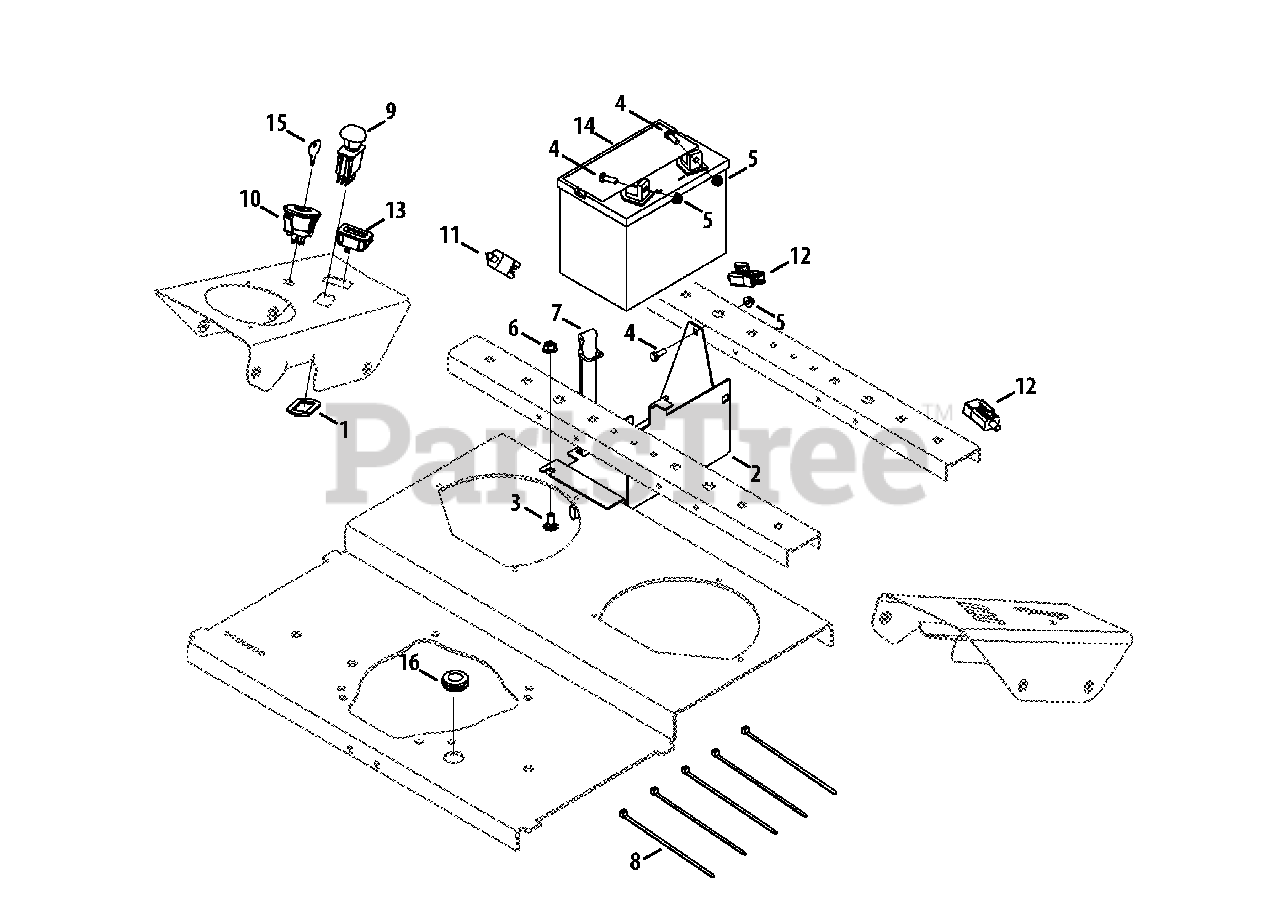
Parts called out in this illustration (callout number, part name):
1	PTO Switch Bracket
2	Battery Bracket
3	Carriage Bolt, 3/8-16 x .750
4	Hex Cap Screw, 1/4-20 x .75
5	Nut, 1/4-20, Flangelock
6	Nut, 3/8-16, Flangelock
7	Battery Strap
8	Cable Tie
9	Electric PTO Switch
10	Key Switch
11	Switch, NC/NO/NO
12	Plunger Switch, NO/NC
13	Hour Meter
15	Key, Assembly
16	Rubber Grommet, .75 x 1.062 x .50
